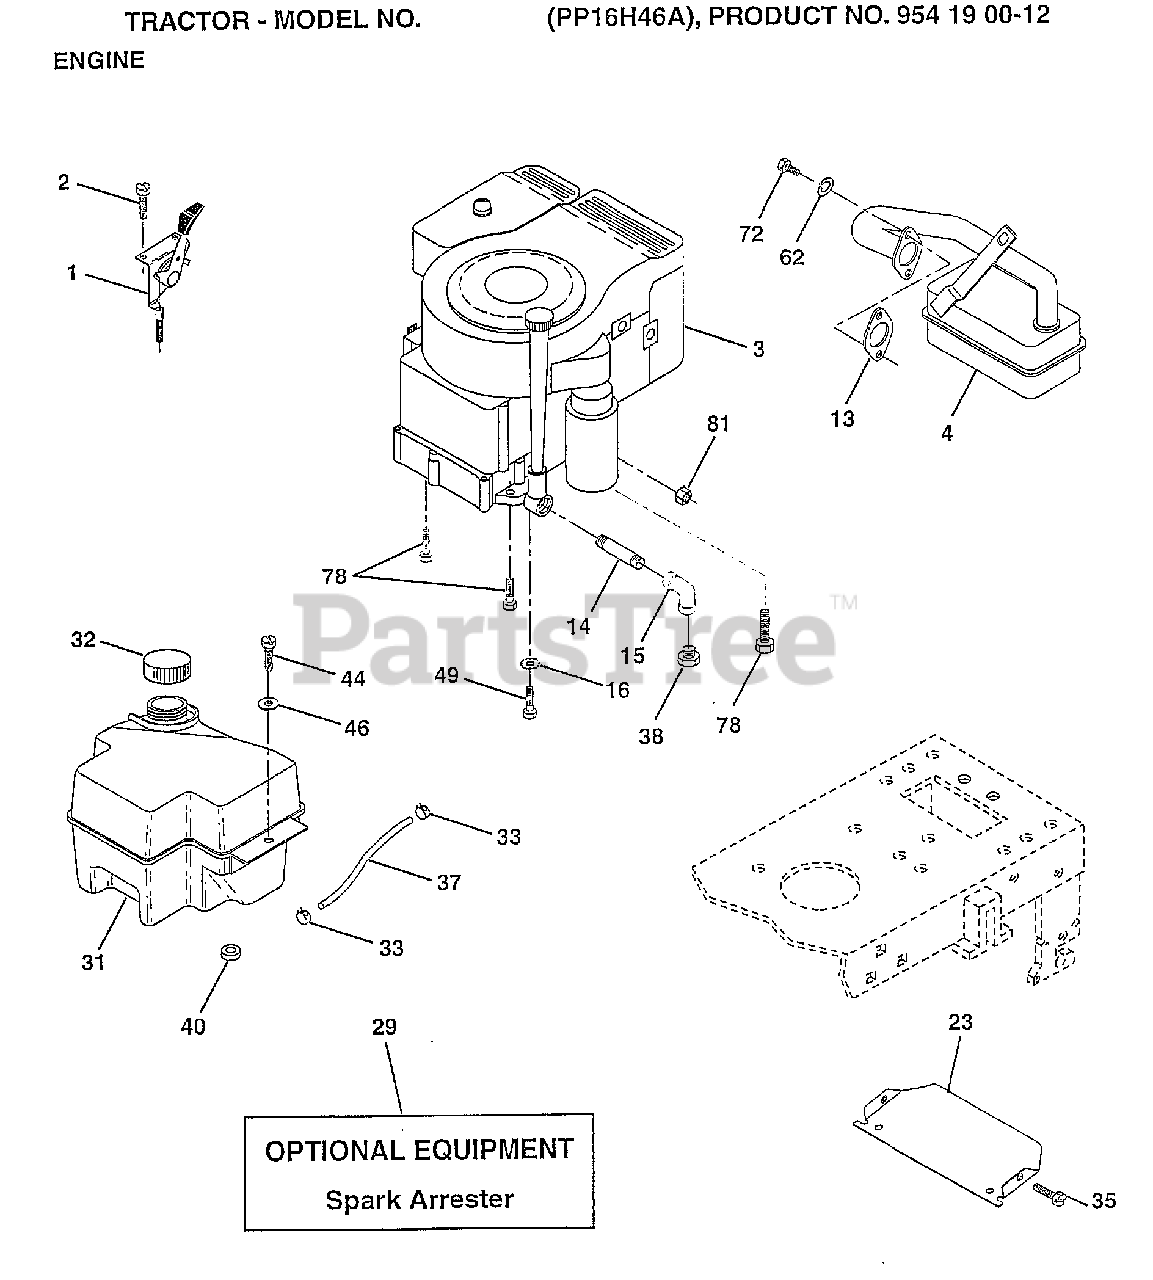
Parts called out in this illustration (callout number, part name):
1	CONTROL THROTTLE
2	SCREW LT
4	MUFFLER
13	GASKET ENG 1 313 LD TIN PLATED
14	PIPE NIPPLE
15	ELBOW
16	LOCKWASHER
23	SHIELD-HEAT
32	CAP ASM FUEL
33	HOSE CLAMP
35	SCREW
37	LINE FUEL
44	SCREW HEX CRT
46	WASHER
49	SCREW GTV
62	LOCKWASHER
72	SCREW
78	SCREW
81	NUT
